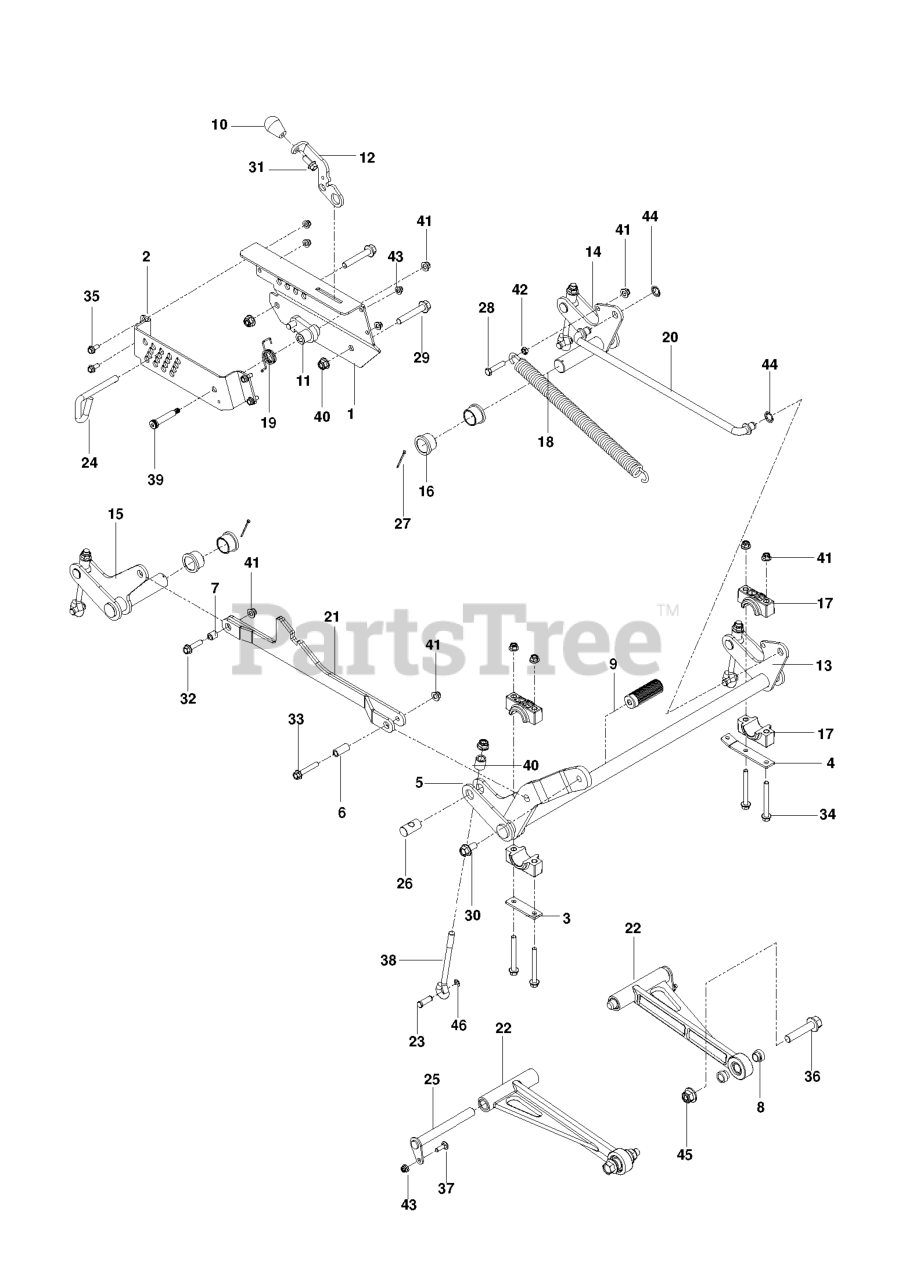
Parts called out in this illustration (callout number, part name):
1	PLATE, HEIGHT INNER ORG
2	PLATE, HEIGHT OUTER ORG
3	PLATE, PILLOW BLACK
4	PLATE, SPRING ANCHOR
5	SPACER, EYEBOLT
6	SPACER, FRONT LIFT STRAP
7	SPACER, REAR LIFT STRAP
8	SPACER, STRUT
9	PEDAL, DECK HEIGHT
10	KNOB - SHIFT
11	LATCH, TRANSPORT WLDMT
12	LEVER, TRANSPORT RELEASE
13	SHAFT DECK LIFT FT
14	SHAFT, LIFT LEFT REAR
15	SHAFT, LIFT RIGHT REAR
16	BUSHING, FLANGE 1.25 X 1.0
17	BLOCK, PILLOW
18	SPRING, EXTENSION
19	SPRING, TORSION
21	WELDMT, DECK STRAP
22	ASSEMBLY, STRUT
23	PIN, 7/16 CLEVIS
24	PIN, HEIGHT
25	PIN, STRUT
26	PIN, TRUNION, EYEBOLT
27	COTTER PIN 1/8 X 2
28	HCS 3/8-16 X 1 3/4 GR5
29	HFFS 1/2-13 X 3 GD 5 ZD
30	HHFS 1/2-13 X 1 GR5 ZD
31	HHFS 3/8-16 X 1 GRD 5 ZD
32	HHFS 3/8-16 X 1.50 GR5 ZD
33	HHFS 3/8-16 X 2-1/4 GR 5 ZD
34	HHFS 3/8-16 X 3.5 GD 5 ZD
35	HHFS 5/16-18 X 3/4
36	HHFS 5/8-11 X 3.0 GD 8 ZD
37	RHSNB 5/16C X 1
38	EYEBOLT, DECK LIFT
39	BOLT, SHOULDER, 1/2 X 2.25
40	NUT, 1/2-13 HEX FLG NYLOC ZD
41	NUT 3/8-16 HEX FLG NYLOC ZD
42	NUT 3/8-16 HEX JAM
43	5/16-18 NYLOC FLANGE NUT
44	NUT 5/8 PUSH
45	NUT 5/8-11 FLG NYLOC ZD
46	RING, E, 7/16
